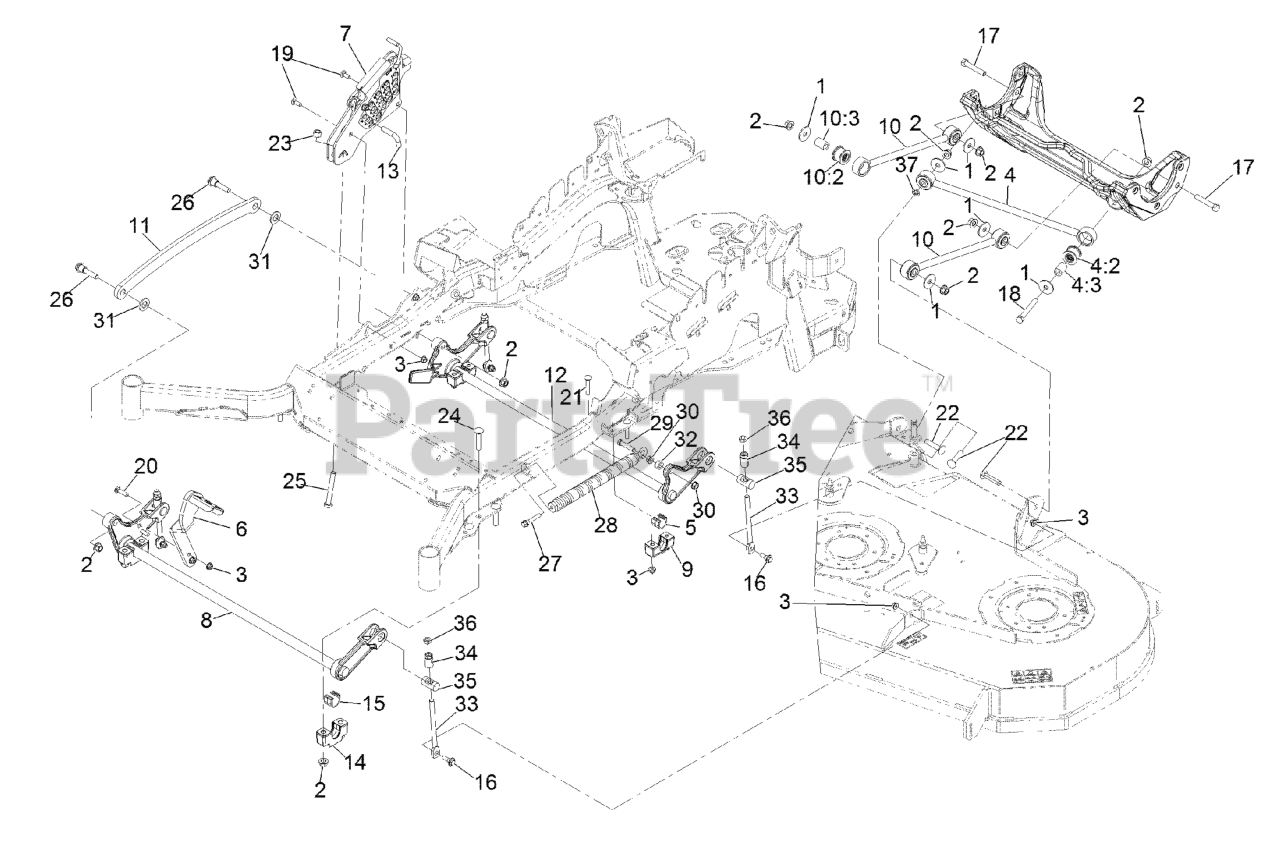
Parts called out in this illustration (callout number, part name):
1	WASHER-THRUST
2	Nut-Lock 1/2-13
3	NUT-HF, NI
4	PANHARD ROD ASM
4:2	BUSHING-SUSPENSION, RUBBER
5	BEARING-CROSS SHAFT, REAR
6	LEVER-FOOT
7	HOC ASM
8	DECKLIFT-FRONT
9	SUPPORT-CROSS SHAFT, BEARING REAR
10	DECK STRUT ASM
10:2	BUSHING-SUSPENSION, RUBBER
11	LINK-LIFT, DECK
12	LIFT-DECK, REAR
13	PIN-HOC
14	SUPPORT-CROSS SHAFT, BEARING
15	BEARING-CROSS SHAFT, FRON
16	SCREW-SHOULDER, HHF
17	SCREW-HH
18	SCREW-HH
19	BOLT-CARR
20	SCREW-CARR
21	Bolt-Carriage 3/8-16 X 2 1/4
22	SCREW-CARR
23	NUT-LOCK, NI
24	Bolt-Carriage 1/2-13 X 2 1/2 Spl Neck
25	BOLT-TAP
26	SCREW-HHF, SHOULDER
27	BOLT-SHOULDER
28	SPRING-EXTENSION
29	SCREW-HH
31	WASHER-FLAT
33	LINK-ADJUSTER, DECK LIFT
34	ADJUSTER-LIFT, DECK
35	TRUNNION
36	NUT-JAM
37	NUT-PUSH
